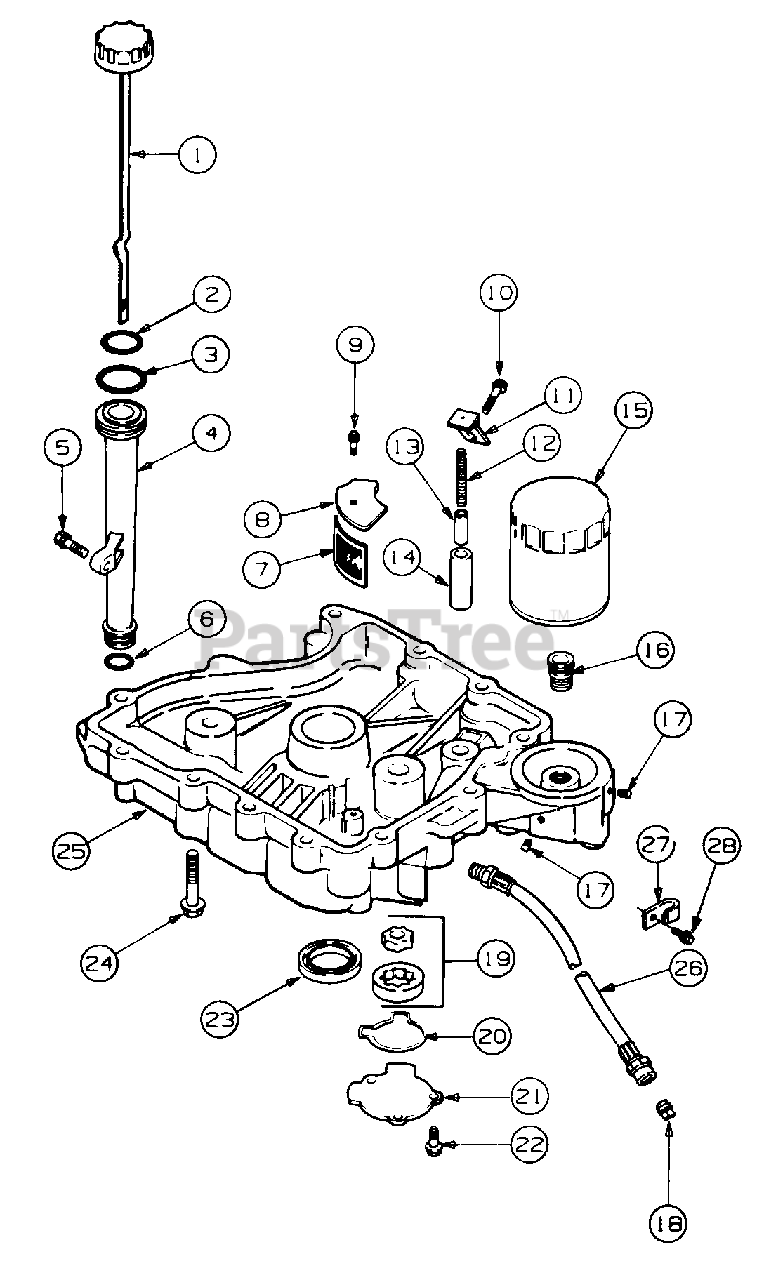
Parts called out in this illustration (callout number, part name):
1	Dipstick Assy
2	O-Ring, Dipstick
3	O-Ring, Upper Oil FillTube
4	Tube, Oil Fill
5	Screw, Oil Fill Tube, M5 X 0.8 X 20
6	O-Ring, Lower Oil Fill Tube
7	Screen, Oil Pickup
8	Cover, Oil Pickup Screen
9	Screw, Screen Cover
10	Screw, Oil Pump Relief Valve Bracket, M10 X 1.5 X 25
11	Bracket, Oil Pump Relief Valve
12	Spring, Oil Pump Relief Valve
13	Piston, Oil Pump Relief Valve
14	Body, Oil Pump Relief Valve
15	Filter, Oil
16	Adapter, Oil Filter
17	Plug, Sp Hd Solid, 1/8 NPTF
18	Plug, Sp Hd Solid, 3/8 NPTF
19	Pump, Oil Assy
20	O-Ring, Oil Pump Cover
21	Cover, Oil Pump
22	Screw, Oil Pan, M8 X 1.25 X 45
23	Seal, Oil (PTO end)
24	Screw, Oil Pan, M8 X 1.25 X 45
26	Hose, Oil Drain
27	Clip, Drain Hose
28	Screw, Hex Wash Hd Tapp, 5/16-18 X .50 Lg
